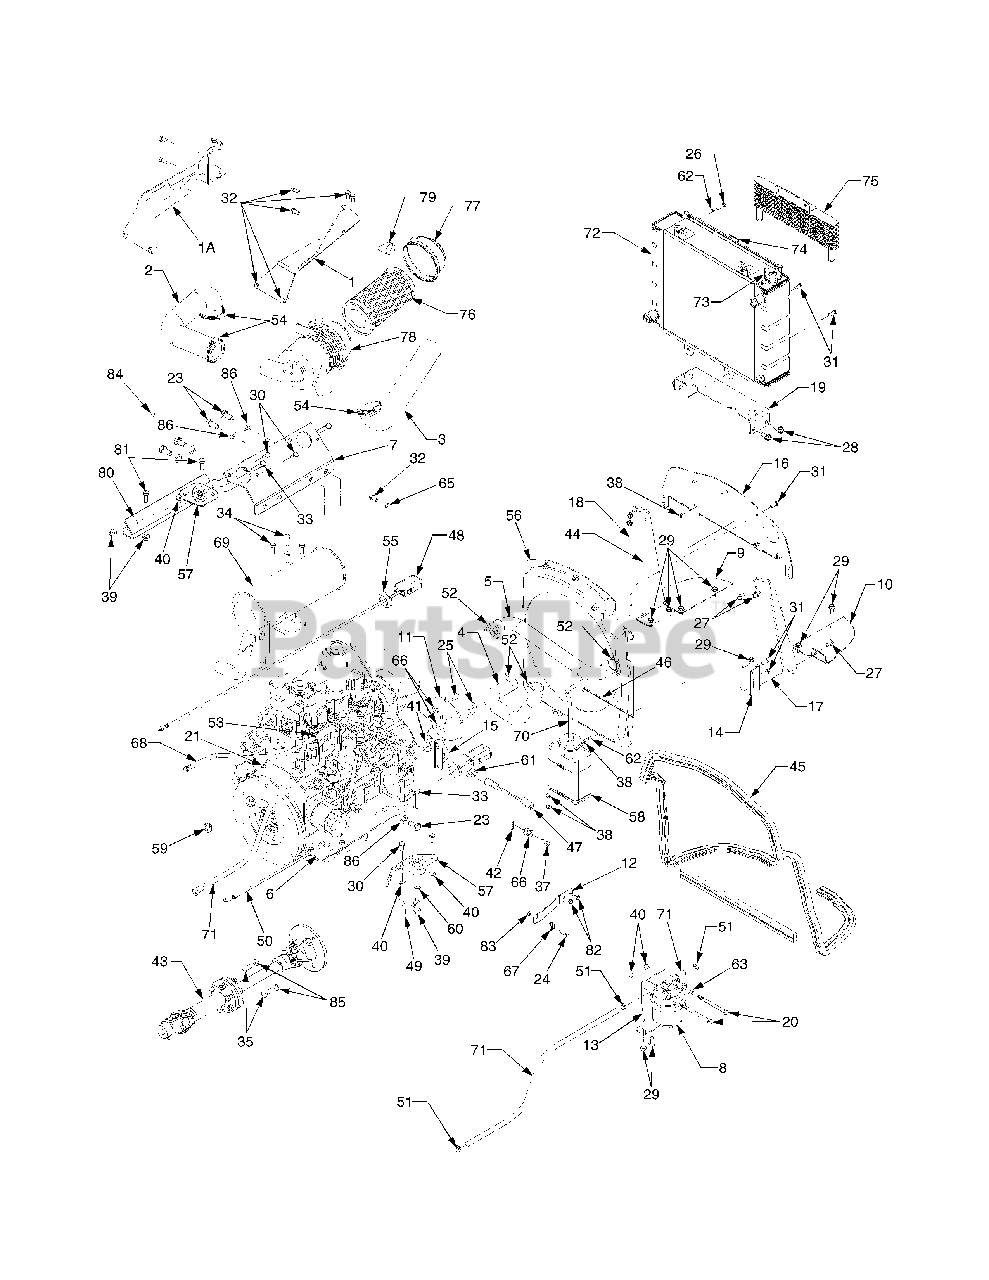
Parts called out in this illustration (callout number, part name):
1	Bracket, Air Filter Mtg. Code C315 and Before
1A	Bracket, Air Filter Mtg. Code D015 and After
2	Hose, Air Inlet
3	Hose, Air Filter
4	Hose, Radiator to Engine
5	Hose, Engine to Radiator
6	Bracket, Engine RH
7	Bracket, Engine LH
8	Filter Assembly, Fuel
9	Plate, Baffle RH
10	Plate, Baffle, LH
11	Plate, Engine RPM
12	Bracket, Cable Mtg.
15	Bracket, Sensor Mtg.
16	Plate, Radiator Baffle
17	Bracket, Radiator Mtg. RH
18	Bracket, Radiator Mtg. LH
19	Bracket, Radiator Mtg.
20	Screw, Hex Cap,5/16-18 x 4.0 Gr5
21	Screw, Hex Wash Hd Tapp 10-16 x .5
23	Screw, Hex Cap,M12-1.25 x 25 GR8.8
24	Screw, Mach. #10-24 x 1.0 GR5
25	Screw, Countersink Torx Hd M8-1.25 x 20
26	Screw, Hex Cap 1/4-20 x 1.0 Gr5
27	Screw, Hex Wash Hd Tapp 5/16-18 x .5
28	Screw, Hex Wash Hd Tapp 3/8-16 x .75
29	Screw, Hex Wash Hd Tapp 5/16-18 x .75
30	Screw, Hex Cap 5/16-18 x .75 GR5
31	Screw, Hex Cap 1/4-20 x .75 GR5
32	Screw, Hex Cap, M8-1.25 x 16
33	Screw, Hex Cap 3/8-16 x 2/0 GR5
34	Screw, Hex Cap,M8-1.25 x 25 GR8.8
35	Screw, Hex Cap, M10-1.5 x 25Gr5
37	Pin, Clevis, .312 x 1.0
38	Nut, Hex Insert Lock, 1/4-20
39	Nut, Hex Flange Lock, 3/8-16 ..
40	Nut, Hex Flange Lock, 5/16-18
41	Nut, Jam, 5/8-18 GR5
42	Pin, Internal Cotter
43	Shaft, Drive
44	Tape, Foam, .625 wide 42 inches
45	Seal, Heat Baffle 104 inches
46	Tie, Cable
47	Sensor, RPM
48	Wire, Battery Pos.
49	Wire, Ground
50	Wire, Battery Neg.
51	Clamp, Hose
52	Clamp, Hose
53	Clamp, Hose
54	Clamp, Adjustable Hose
55	Grommet, Hose Guard
56	Shroud, Fan
57	Mount, Compression Engine ...
58	Container, Over Flow
59	Grommet, Rubber
60	Washer, External Lock, 3/8
61	Washer, Lock, 5/8
62	Washer, Flat, .28 x .74 x .063 .
63	Washer, Flat, .344 x .688 x .065
65	Washer, External Lock, 5/16 ...
66	Washer, Flat, .344 x .75 x .12 .
67	Clamp, Casing
68	Hose, Fuel Line Return 81 inches
69	Muffler, Engine
70	Hose, Over Flow 18 inches
71	Fuel Line, 5/16 ID 83 inches
73	Cap, Radiator, 13psi
74	Screen, Debris
75	Cooler, Oil
76	Element, Air Cleaner
77	Cap, Air Cleaner
78	Canister, Air Cleaner
79	Nozzle, Air Cleaner
80	Bracket, Engine Mtg.
81	Screw, Hex Cap, 3/8-16 x 1.0 Gr5
82	Screw, Hex Cap,M6-1.0 x 10mm GR8.8
83	Nut, Hex Insert Lock, #10-24
84	Nut, Flange Lock, M6-1.0
85	Washer, Flat, .375 x .738 x .063
86	Washer, Flat, .535 x .93 x .09 .
